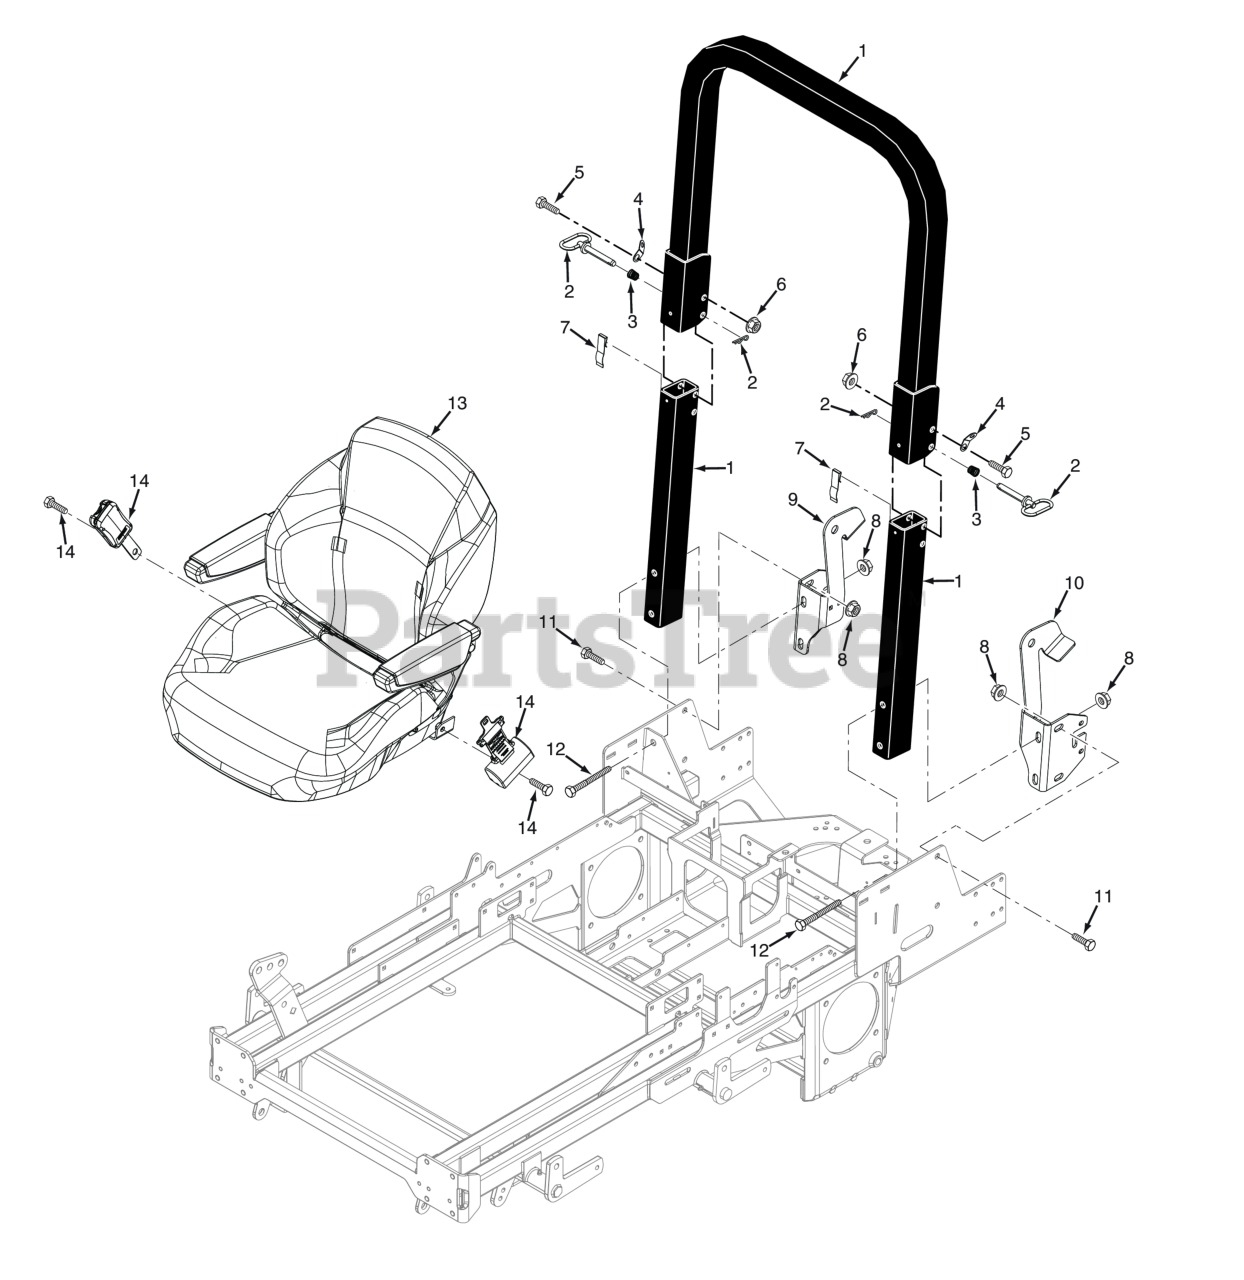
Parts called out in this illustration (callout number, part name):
1	ROPS, Foldable SCZ
2	Pin Assembly, ROPS Hinge
3	Spring, ROPS
4	Clip, ROPS
5	Bolt, Hex Head, 1/2-13 x 3-1/4"
6	HEX LOCKNUT, ELASTIC STOP, 1/2-13
7	Spring, ROPS Anti-Rattle
8	Nut, Elastic Stop 1/2-13, (STT-52 & STTII-52)
9	ROPS Mount, RH, 29CV-EFI
10	ROPS Mount, LH, 29CV-EFI
11	Bolt, Hex Head 1/2-13 x 1-1/4"
12	Bolt, Hex Head 1/2-13 x 4-1/4"
13	Seat Assembly (INCL 14)
14	Seat Belt Kit, Retractable - SCZII
